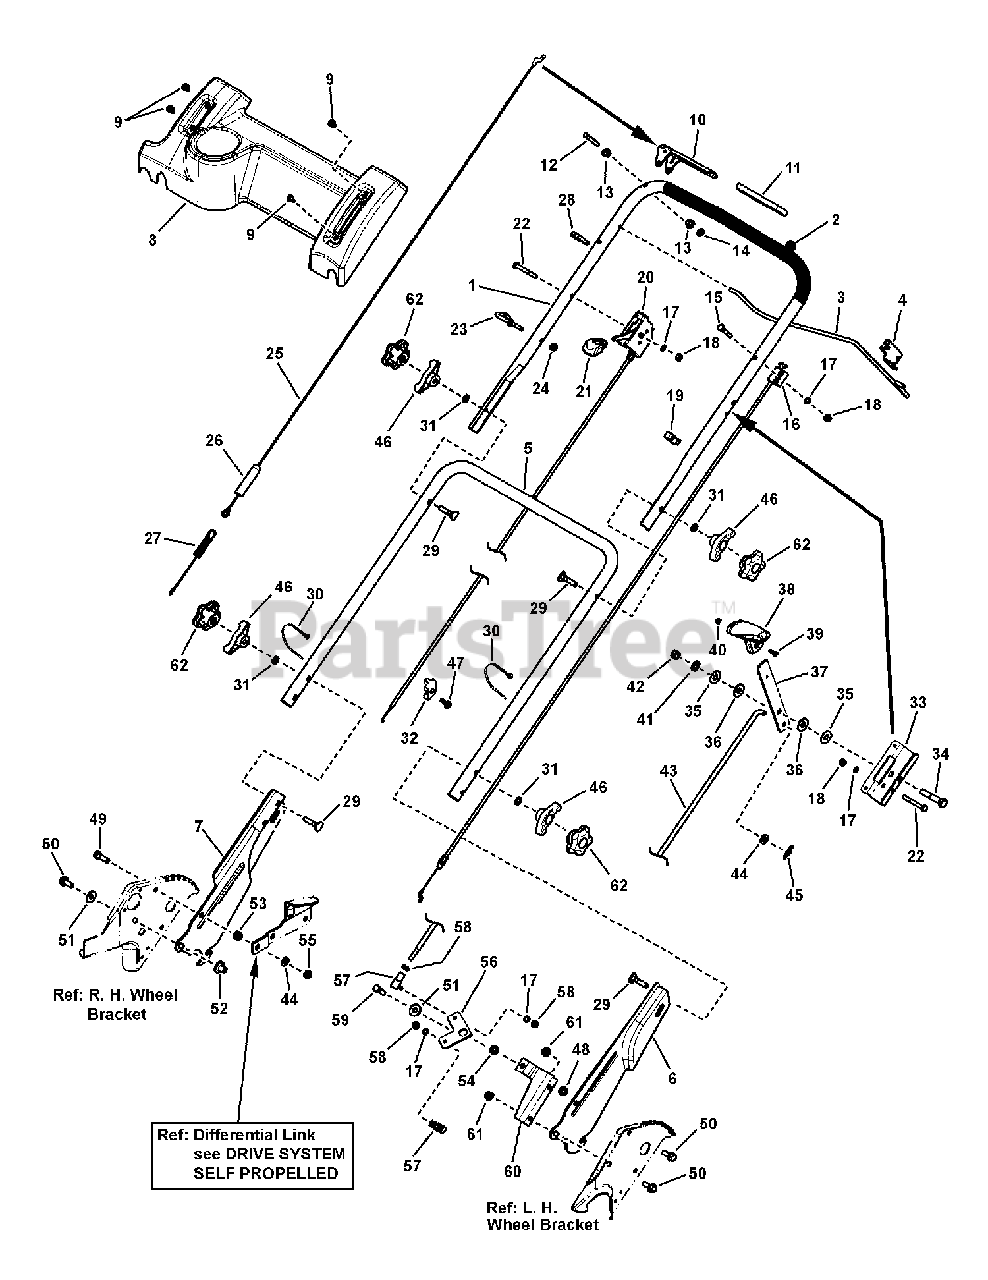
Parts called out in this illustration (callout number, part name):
1	HANDLE, Upper
2	FOAM GRIP, 18.75 long
3	BAIL, OPC Control
4	CLIP, Zone Control
5	HANDLE, Middle
6	HANDLE, Lower LH (Adjustable)
7	HANDLE, Lower RH (Adjustable)
8	CONTROL PANEL (w/o Electrical Switch Hole)
8	CONTROL PANEL (w/Electrical Switch Hole)
8	CONTROL PANEL (w/o wheel drive slot)
9	SCREW, 1/4-20 x 1/2 Pan Head Self-Tap (Torx)
10	HANDLE, Clutch
11	GRIP, International Symbol
12	PIN, 1/4 x 1-1/2"
13	BUSHING, .27 x .35 x .4 Flange
14	PUSH-NUT, 1/4"
15	SCREW, 1/4-20 x 1-1/2 Hex Head Cap GR 5
16	* CABLE, Zone Control (52-63/64 Long)
16	* CABLE, Zone Control (52-21/32 Long)
16	* CABLE, Zone Control (50-31/64 Long)
17	WASHER, 1/4 Internal Tooth Lock
18	NUT, 1/4-20 Hex
19	CLIP, Wiring Harness
20	THROTTLE CONTROL, RP, D.O.V. Engine (50.0)
20	THROTTLE CONTROL, (62.0)
21	THROTTLE KNOB, (Red)
22	SCREW, 1/4-20 x 2 Hex Head Cap, GR 5
23	GUIDE, Rope (1/4-20 thread)
24	NUT, 1/4-28 Hex GR 5 or B
25	CABLE, Clutch Control (41-1/4 Long)
26	COVER, Vinyl
27	SPRING, Clutch - 21S
28	CLAMP, 7/8 Double Cable
29	SCREW, 5/16-18 x 1-7/8 Curved Head GR 2
30	CABLE-TIE, 7"
31	WASHER, 5/16 Internal Tooth Lock
32	CLAMP, Casing
33	BRACKET, Shift
34	SCREW, 3/8-16 x 2 Hex Head Cap, GR 5
35	WASHER, 7/16 Flat
36	WASHER, Nylon
37	LEVER, Shift
38	KNOB, Shift (Red)
39	SCREW, #8-32 x 1/2 Cross Recess Filister Head Machine
40	NUT, #8-32 Hex
41	WASHER, Belleville
42	NUT, 3/8-16 Hex Center Lock
43	ROD, Speed Control (1/4-28 thread)
44	WASHER, 11/32 Flat
45	COTTER PIN, 5/16 Self Lock
46	KNOB, 5/16-18 Wing (Black)
47	SCREW, #10-32 x .62" Hex Head Self-Tap
48	NUT, 5/16-18 Hex Center Lock
49	SCREW, 5/16-24 x 1 Hex Head Cap GR 5
50	BOLT, 5/16-18 x 3/4 Hex Flange Lock GR 5
51	WASHER, .33 x .88 x .09 Flat
52	TEENUT, 5/16-18
53	BUSHING, Differential, .328 x .625 x .41
54	SPACER, .33 x .63 x .156
55	NUT, 5/16-24 Hex Center Lock GR 5
56	BELL CRANK
57	BALL JOINT, 1/4-28
58	NUT, 1/4-28 Hex
59	SCREW, 5/16-18 x 7/8 Hex Head Cap, GR 5
60	BRACKET, Bell Crank
61	NUT, 5/16-18 Hex Flange Lock, GR 5
62	KNOB, Handle, 5-Prong
